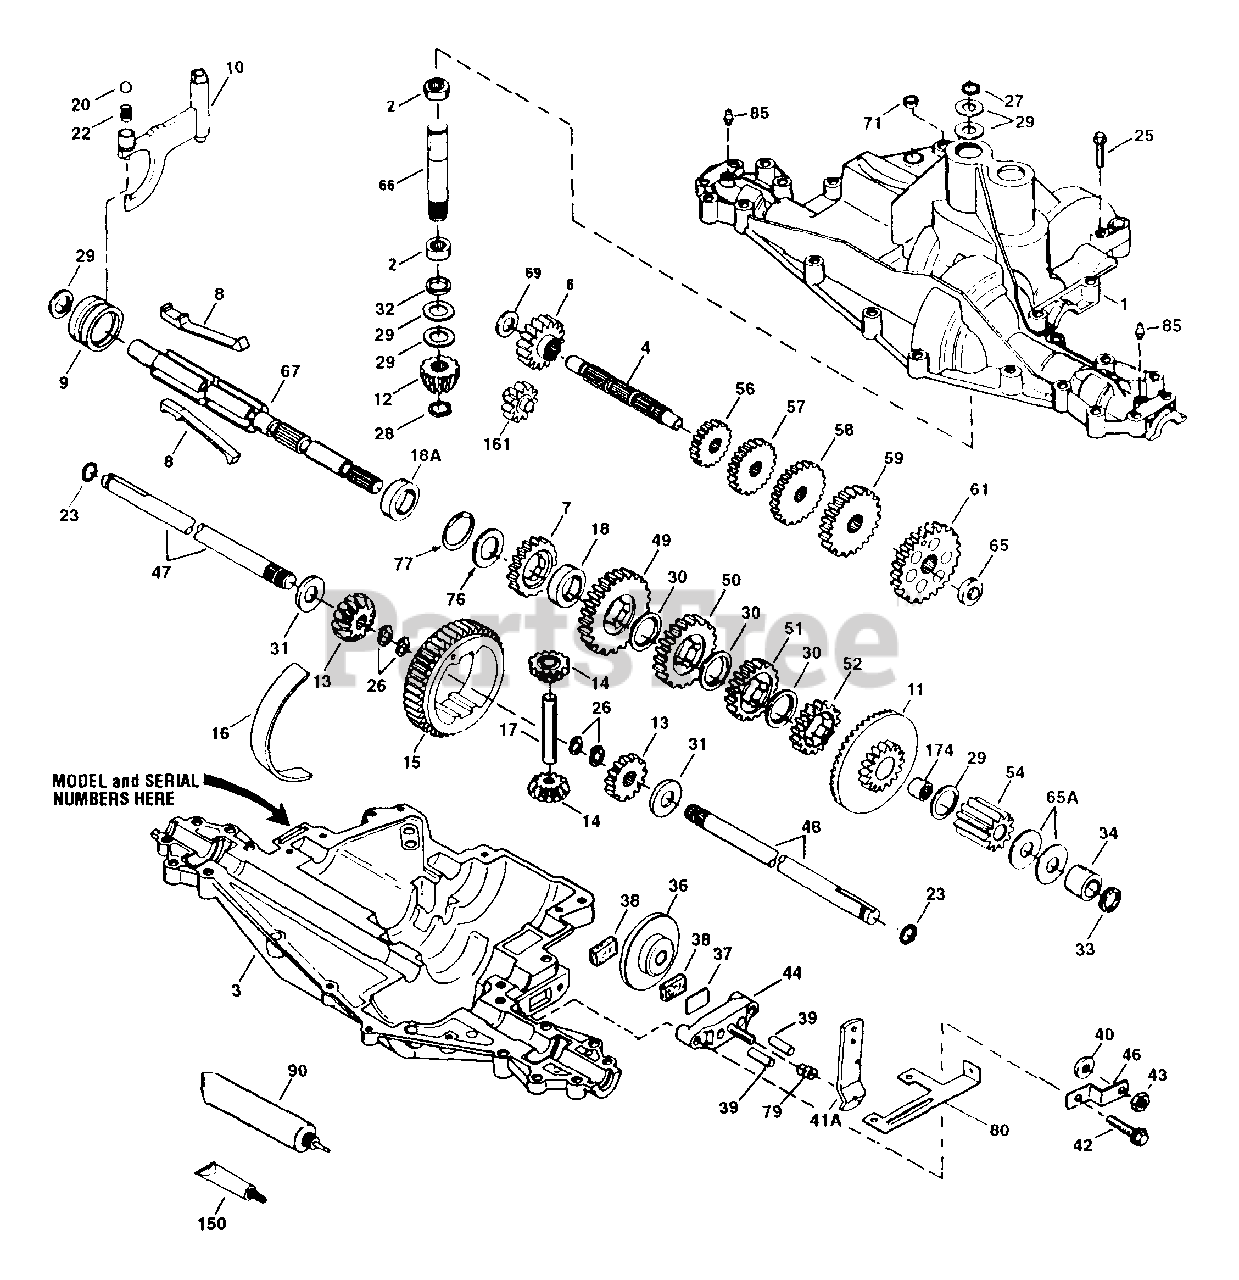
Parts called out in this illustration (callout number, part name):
1	Transaxle Cover
2	Needle Bearing
3	Transaxle Case
4	Countershaft
6	Spur Gear (16 teeth)
7	Spur Gear (22 teeth)
8	Shift Key
9	Shift Collar
10	Shift Rod & Fork
11	Bevel Gear & Bearing
12	Bevel Pinion (14 teeth)
13	Bevel Gear (16 teeth)
14	Differential Pinion
15	Ring Gear
16	Bearing Strip
17	Drive Pin
18	Neutral Spacer
18A	Neutral Spacer
20	Ball, 5/16" dia
22	Spring
23	Seal Ring
25	Screw, 1/4-20 x 1-1/4"
26	Retaining Ring
27	Retaining Ring
28	Retaining Ring
29	Washer
30	Washer
31	Washer
32	O Ring
33	O Ring
34	Bushing
36	Brake Disk
37	Brake Pad Plate
38	Brake Pad
39	Dowel Pin
40	Washer
41	Brake Lever
42	Screw, 1/4-20 x 1-1/4"
43	Locknut, 5/16 24
44	Brake Pad Holder
46	Brake Lever Bracket
47	Axle (16-1/4" long)
48	Axle (11" long)
49	Spur Gear (30 teeth)
50	Spur Gear (25 teeth)
51	Spur Gear (22 teeth)
52	Spur Gear (19 teeth)
54	Spur Gear (11 teeth)
56	Spur Gear (20 teeth)
57	Spur Gear (25 teeth)
58	Spur Gear (28 teeth)
59	Spur Gear (30 teeth)
61	Spur Gear (34 teeth)
65	Washer
65A	Washer
66	Input Shaft
67	Shifter & Brake Shaft
69	Washer
71	Square Cut Ring
76	Washer
77	Inverted Retaining Ring
79	Spring
80	Brake Bracket
85	Lubrication Fitting
90	Grease
150	Gasket Eliminator
161	Reverse Idler
174	Needle Bearing
